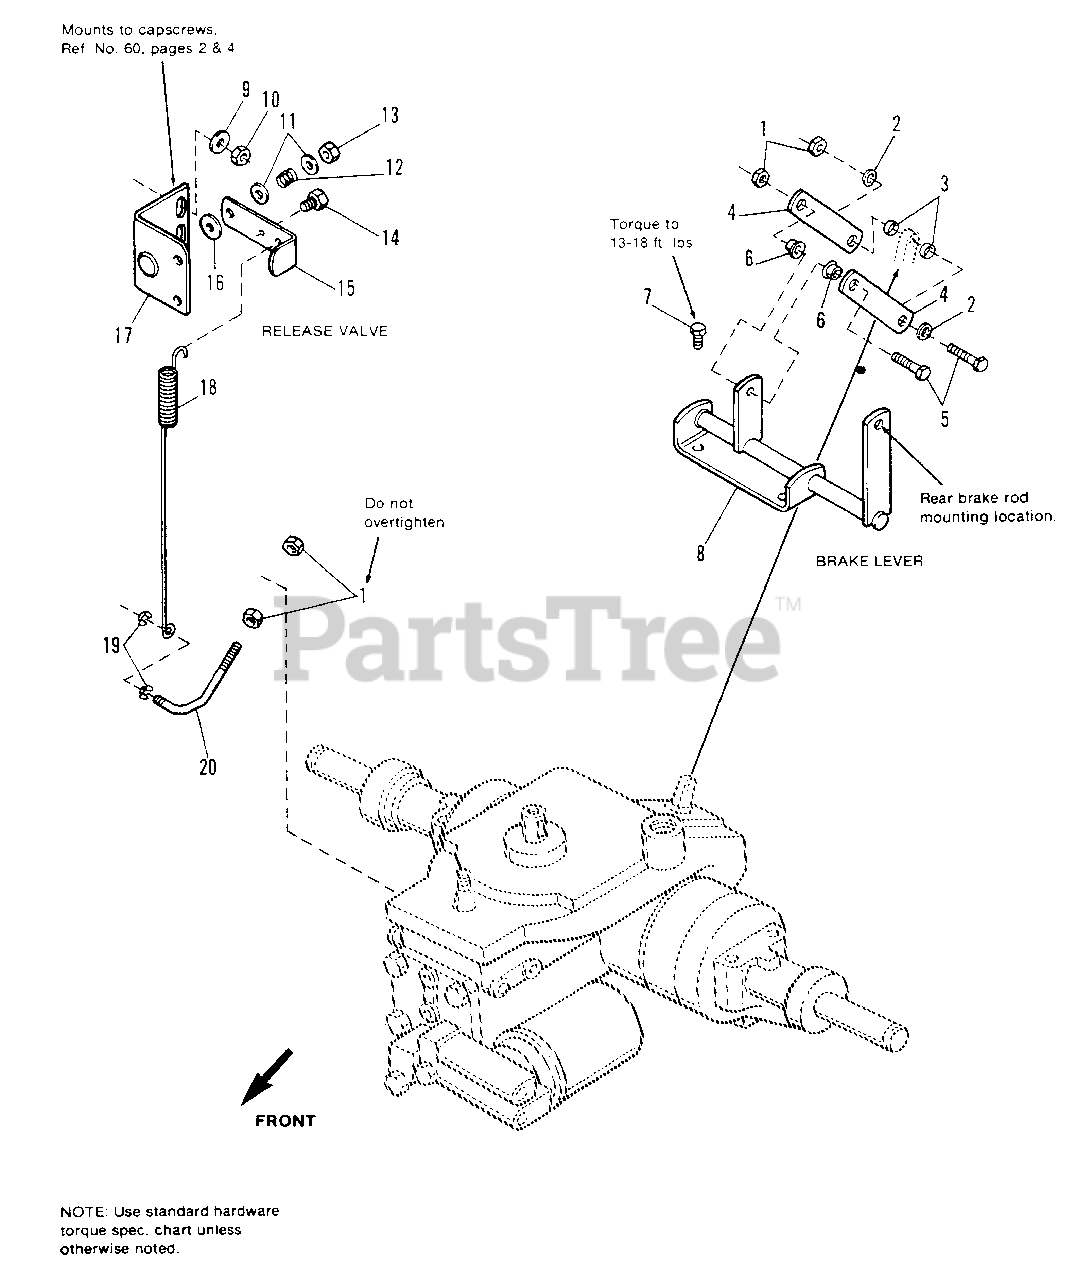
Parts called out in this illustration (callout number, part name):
1	NUT, Hex Lock, 1/4-20
2	WASHER, Flat
4	BRACKET, Brake Clevis
5	CAPSCREW, 1/4-20 x 1-1/4
6	SPACER, Shoulder
7	CAPSCREW, 5/16-18 x 5/8
8	BRACKET ASSY., Brake Lever
10	NUT, Hex, 5/16-18
11	WASHER, 1/4
12	SPRING, Compression
13	NUT, Center Lock, 1/4-20
14	SCREW, Taptite, 1/4-20 x 3/8
15	LEVER, Release Valve
16	WASHER, Nylon
17	BRACKET ASSY., Release Valve
18	SPRING, Tension
20	LEVER, Hydro Release Valve
